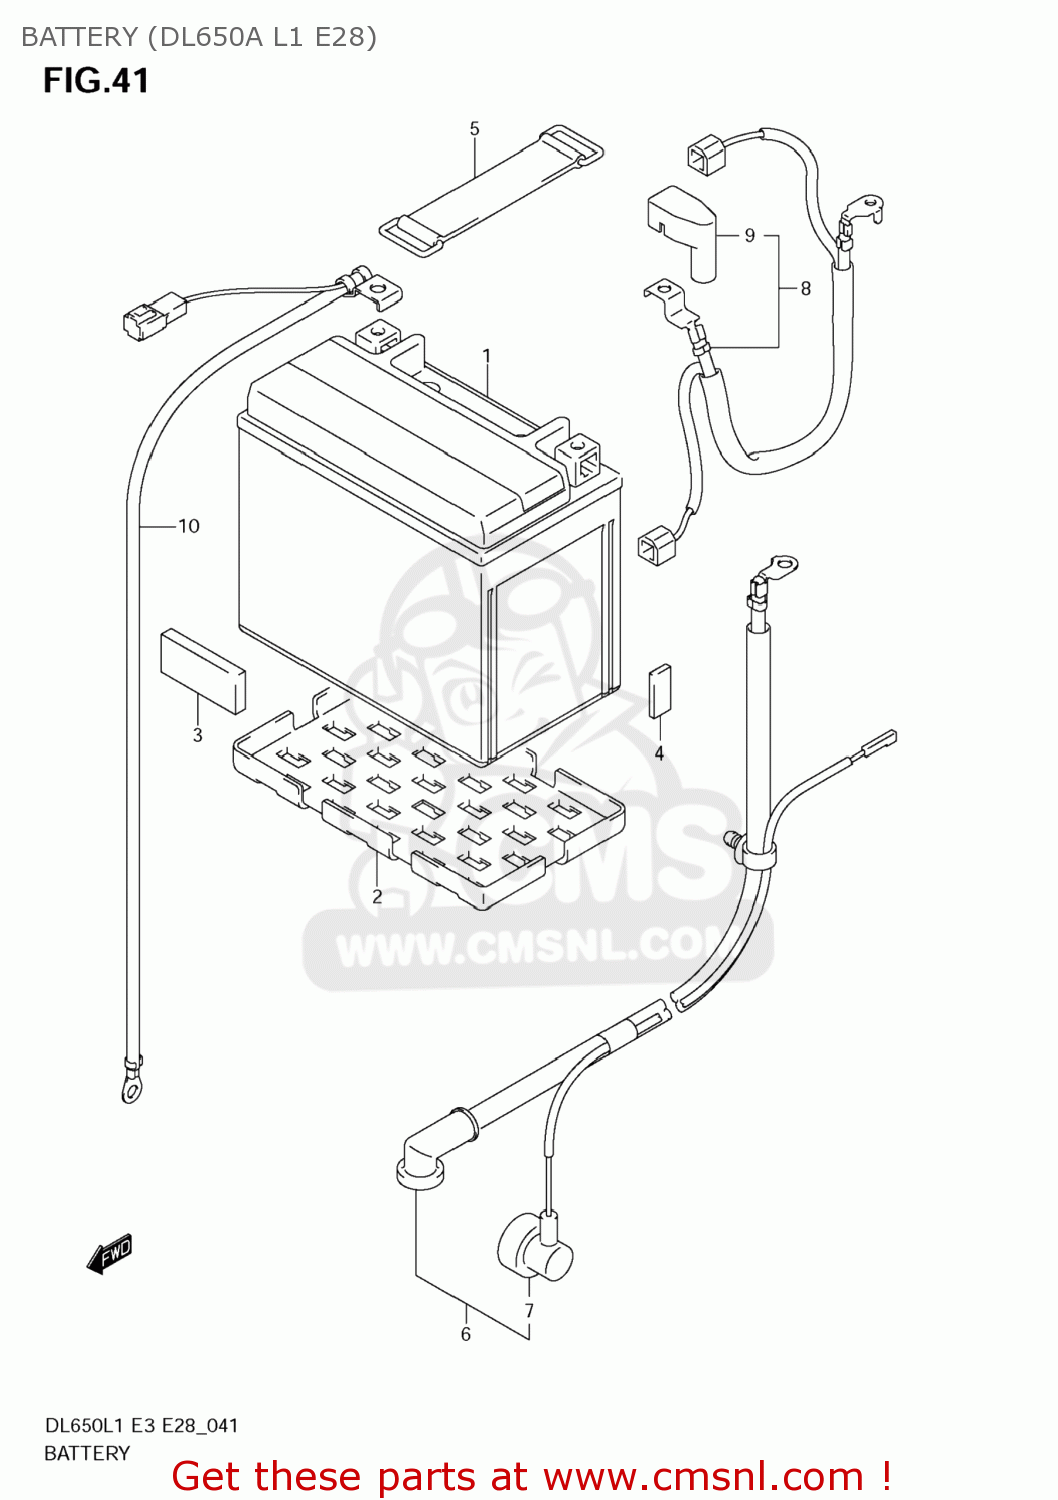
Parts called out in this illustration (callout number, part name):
1	BATTERY ASSY(YTX12-BS,12V10AH)
2	PROTECTOR,BATTERY
3	PROTECTOR,BATTERY(70X100X6)
4	CUSHION,FUEL TANK NO.2
5	BAND
6	WIRE,STARTER MOTOR LEAD
7	CAP,OIL PRESSURE SWITCH
8	WIRE,BATTERY PLUS LEAD
9	CAP,BATTERY PLUS LEAD
10	WIRE,BATTERY MINUS LEAD
